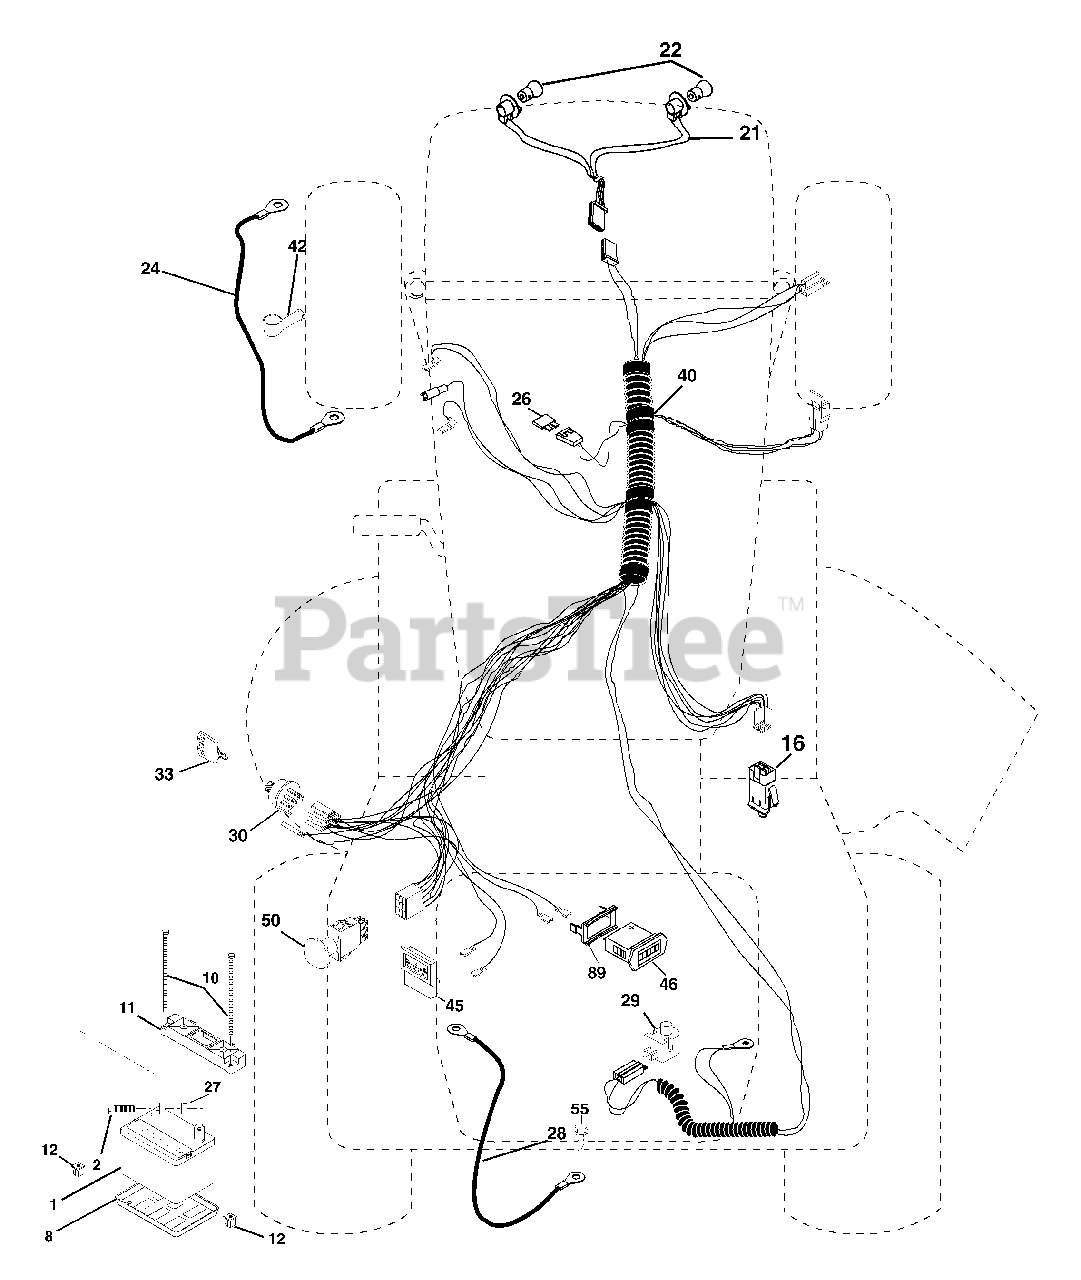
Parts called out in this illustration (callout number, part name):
1	Battery 12 Volt 35 AMP
2	Bolt Hex Hd 1/4-20 unc x 3/4
8	Tray Battery
10	Bolt Brt Frt 1/4-20 x 75 Ainc
11	Holddown Battery Front Mount
12	Nut Push Nylon 1/4" Battery Frt
16	Switch Interlock
21	Harness Asm Light W/4152j
22	Bulb Light #1156
24	Cable Battery
27	Nut Keps Hex 1/4-20 unc
28	Cable Ground 6 Ga 21" black
29	Switch Plunger Nc Gray
30	Switch Ign
33	Key Ign Molded Generic
40	Harness Ign.
42	Cover Terminal Red
45	Ammeter Rectangular 15 Amp
46	Meter Hour
50	Switch PTO
55	Screw Thdrol 5/16-18 x 1-1/2 Tyt
89	Bracket Snap-In Hourmeter
